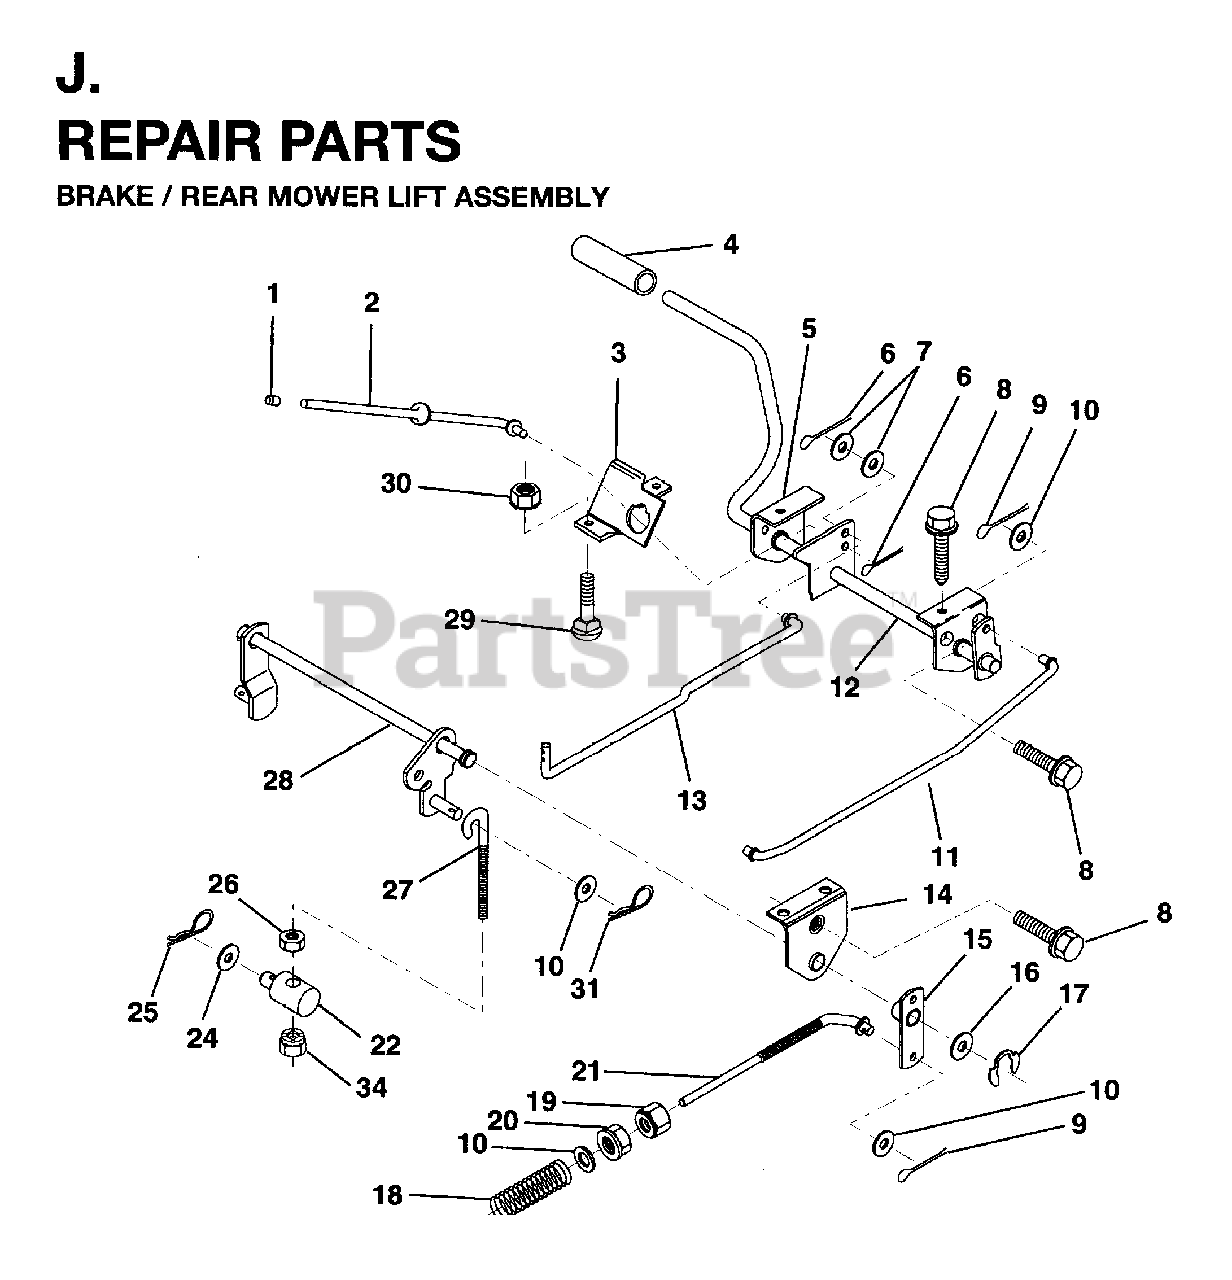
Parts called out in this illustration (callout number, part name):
1	PLUNGER CAP
2	ROD,PARK BRAKE
3	BRKT,PARK BRAKE
4	PEDAL COVER T
5	BRKT,CLU PEDAL LH
6	COTTER PIN
9	COTTER PIN
10	WASHER
11	ROD,FRT BRAKE
12	CLUTCH/BRAKE PEDAL ASSY
13	ROD,CLUTCH
14	BRKT,LIFT SHAFT
15	ARM, BRAKE ASMBLY
17	KLIP RING
18	SPRING, BRAKE ROD
19	NUT.HEX.3/8-16UNC
20	LOCKNUT
21	ROD REAR BRAKE
22	TRUNNION, LEFT
25	SPRING.RETAINER
26	LOCKNUT
27	LINK.MOWER.REAR
28	REAR MOWER LIFT ASSY
30	LOCKNUT
31	SPRING RETAINER
34	LOCKNUT
